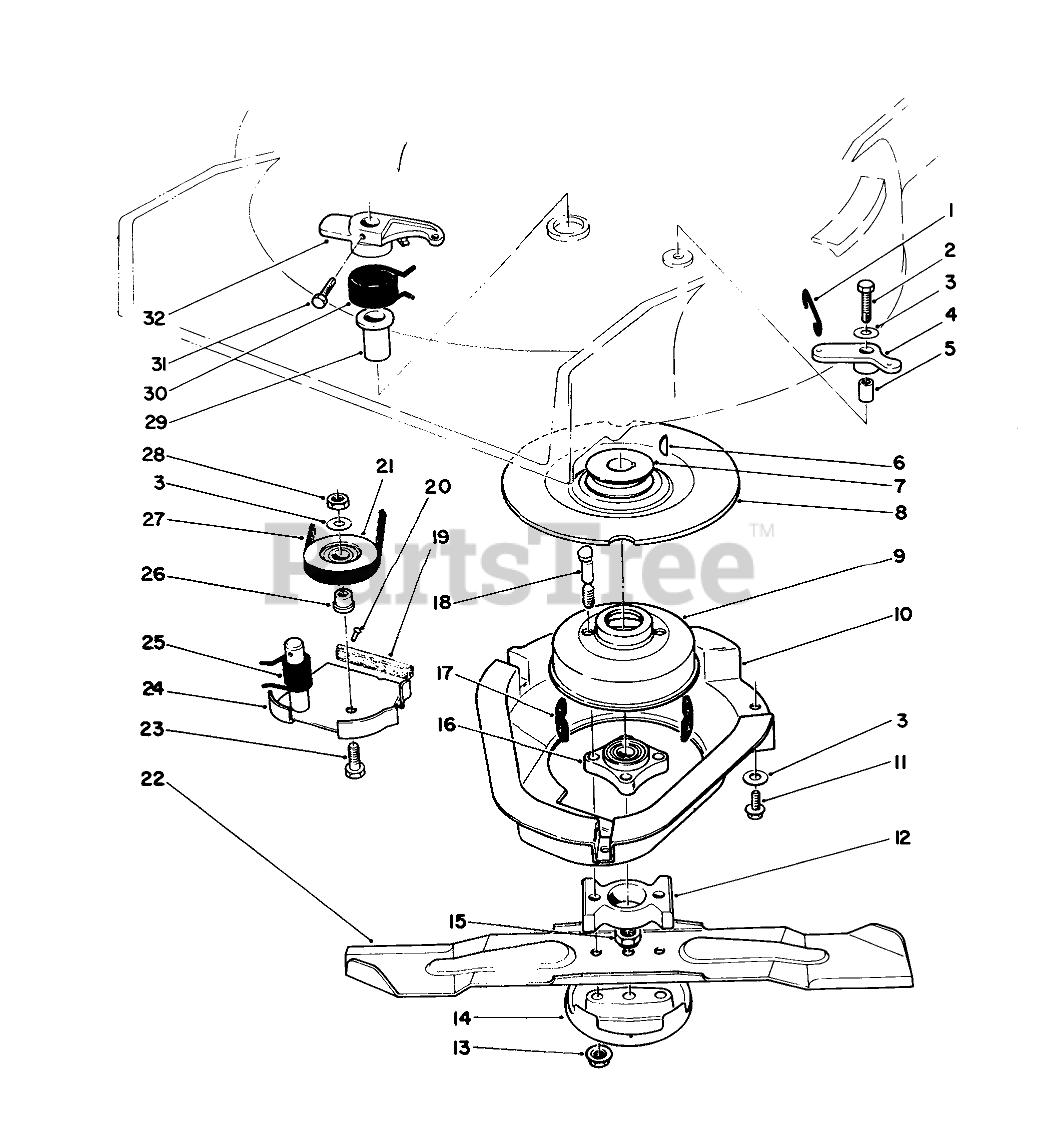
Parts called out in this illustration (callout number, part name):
1	LINK-CONTROL
2	SCREW-HH
3	WASHER-PLAIN
4	BELLCRANK
5	SLEEVE-BELLCRANK
6	KEY-WOODRUFF
7	PULLEY
8	Flywheel
9	Drum-Brake
10	SHIELD BBC
11	SCREW-HWHTF
12	SPACER-BLADE
13	NUT-LOCK
14	Anti Scalp Cup
15	NUT-LOCK, NI
16	HUB ASM
17	DAMPENER-VIBRATION
18	BOLT-BLADE
19	Paid
20	.185 DIA X .375 RT +
21	PULLEY-IDLER
22	BLADE-21in
23	SCREW-HH
24	Brake Plate (Incl. Ref. #19 & 20)
25	SPRING-TORSION
26	HUB-PULLEY, IDLER
27	V-BELT
28	NUT-LOCK, NI
29	BUSHING PM
30	SPRING-TORSION
31	SCREW-HH
32	LEVER
